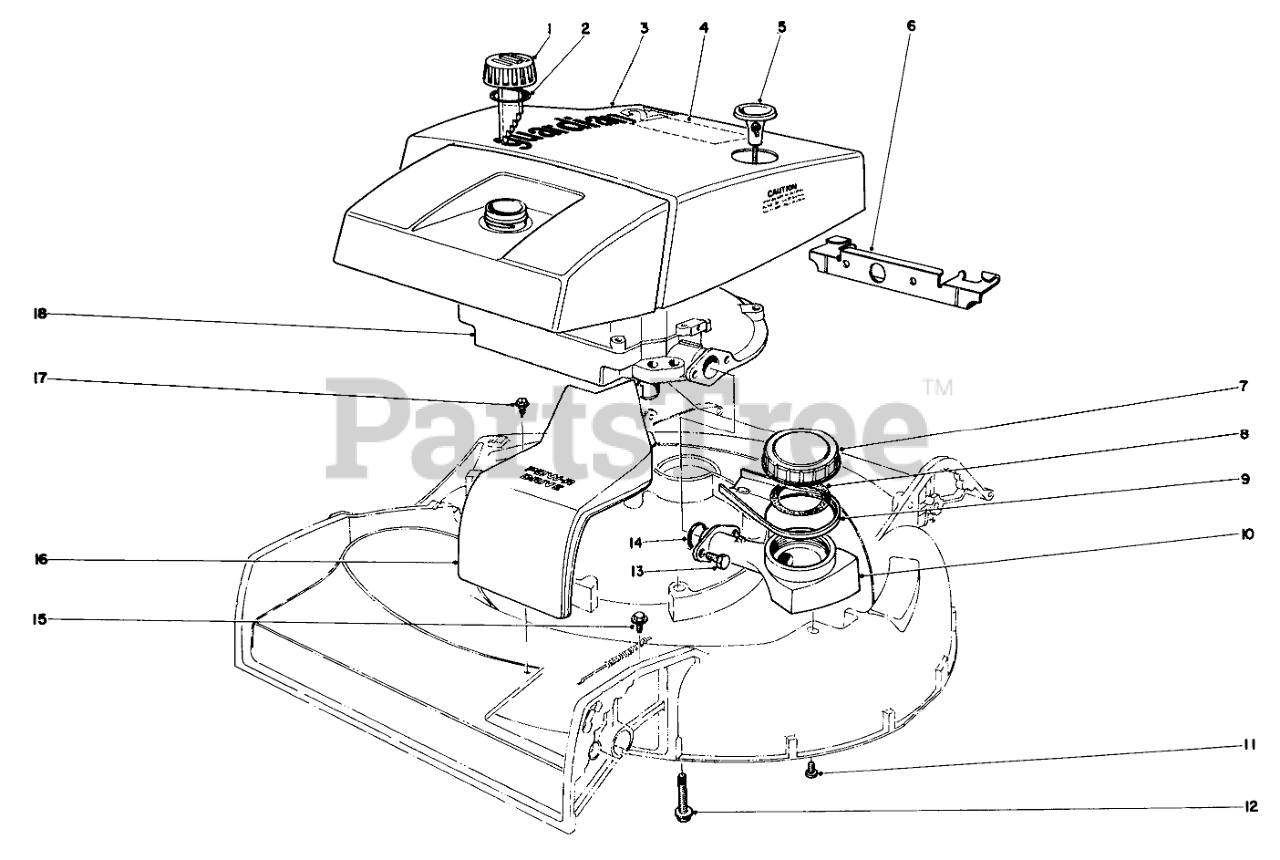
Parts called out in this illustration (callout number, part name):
1	Gas Cap (Incl. Ref. No. 2)
2	Gasket
3	Shroud
4	Decal-Maintenance
5	Rope Handle
6	Shroud Bracket
7	Oil Gauge Cap
8	VISUAL OILER GASKET
9	Spout
10	Oil Gauge
11	Screw
12	3/8-16 X 2-3/4 CAPSCR
13	SCREW-HH
14	O RING
15	Screw
16	Cover
17	SCREW-HWHTF
18	Engine
